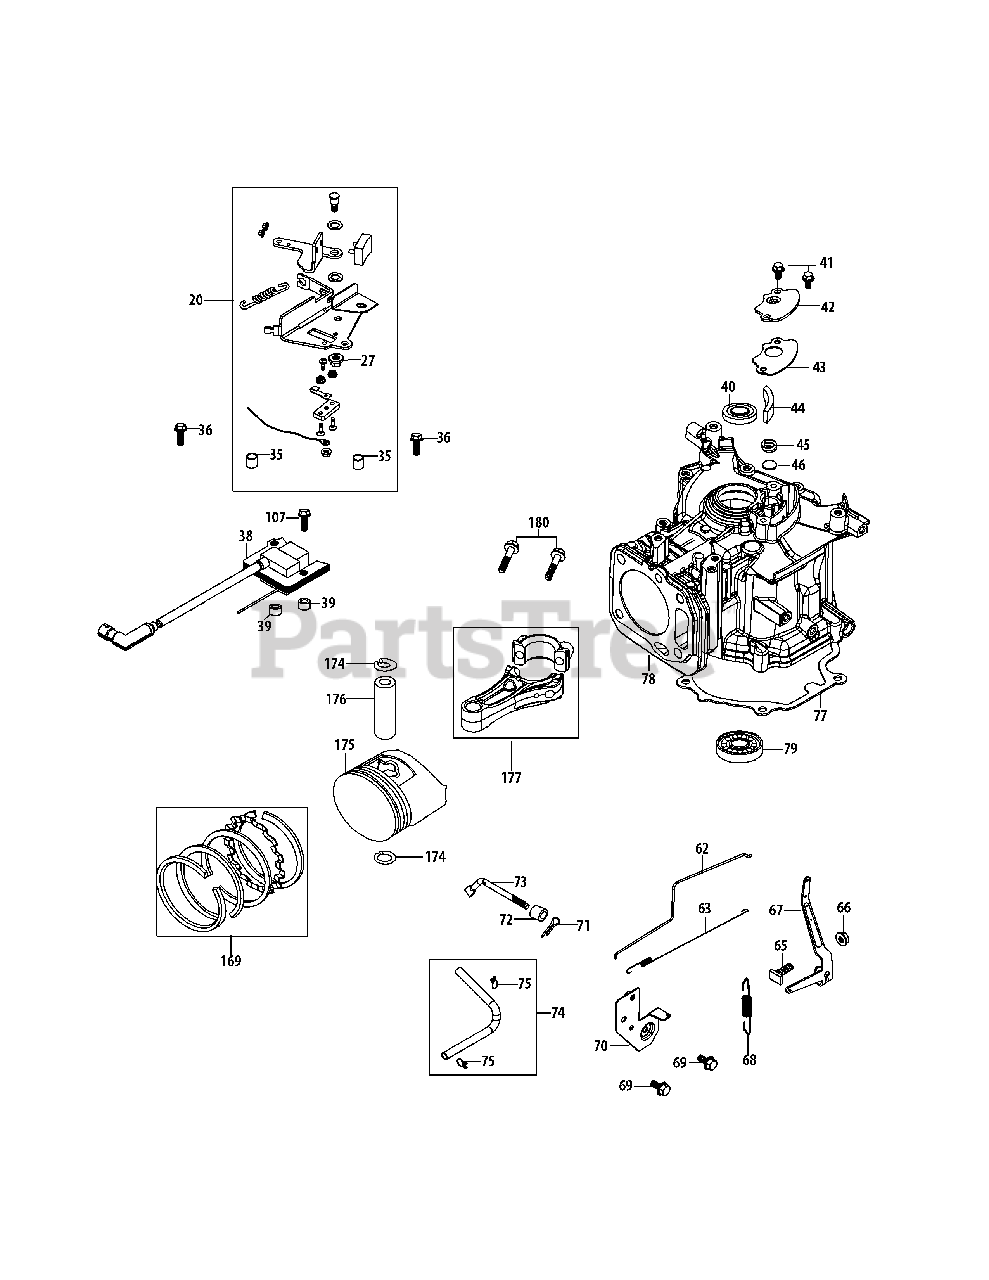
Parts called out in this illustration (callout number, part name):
20	Brake Assembly
27	Brake Arm Nut
35	Brake Spacer
36	Brake Assy Bolt M6×35
38	Ignition Coil Assembly
39	Ignition Coil Spacer
40	Upper Crankshaft Seal
41	Bolt M6×14
42	Breather Cover Plate
43	Breather Gasket
44	Breather Screen
45	Breather Spring
46	Breather Valve
62	Throttle Linkage
63	Throttle Linkage Spring
65	Governor Arm Bolt
66	Governor Arm Nut M6
67	Governor Arm
68	Governor Spring
69	Bolt M6×12
70	Component Bracket
71	Governor Cotter Pin
72	Governor Seal
73	Governor Arm Shaft
74	Breather Hose Assembly
75	Breather Hose Clamp
77	Crankcase Cover Gasket
78	Short Block Assembly
79	Main Bearing
107	Bolt M6×30
169	Piston Ring Set
174	Piston Pin Snap Ring
175	Piston
176	Piston Pin
177	Connecting Rod Assembly
180	Connecting Rod Bolt
